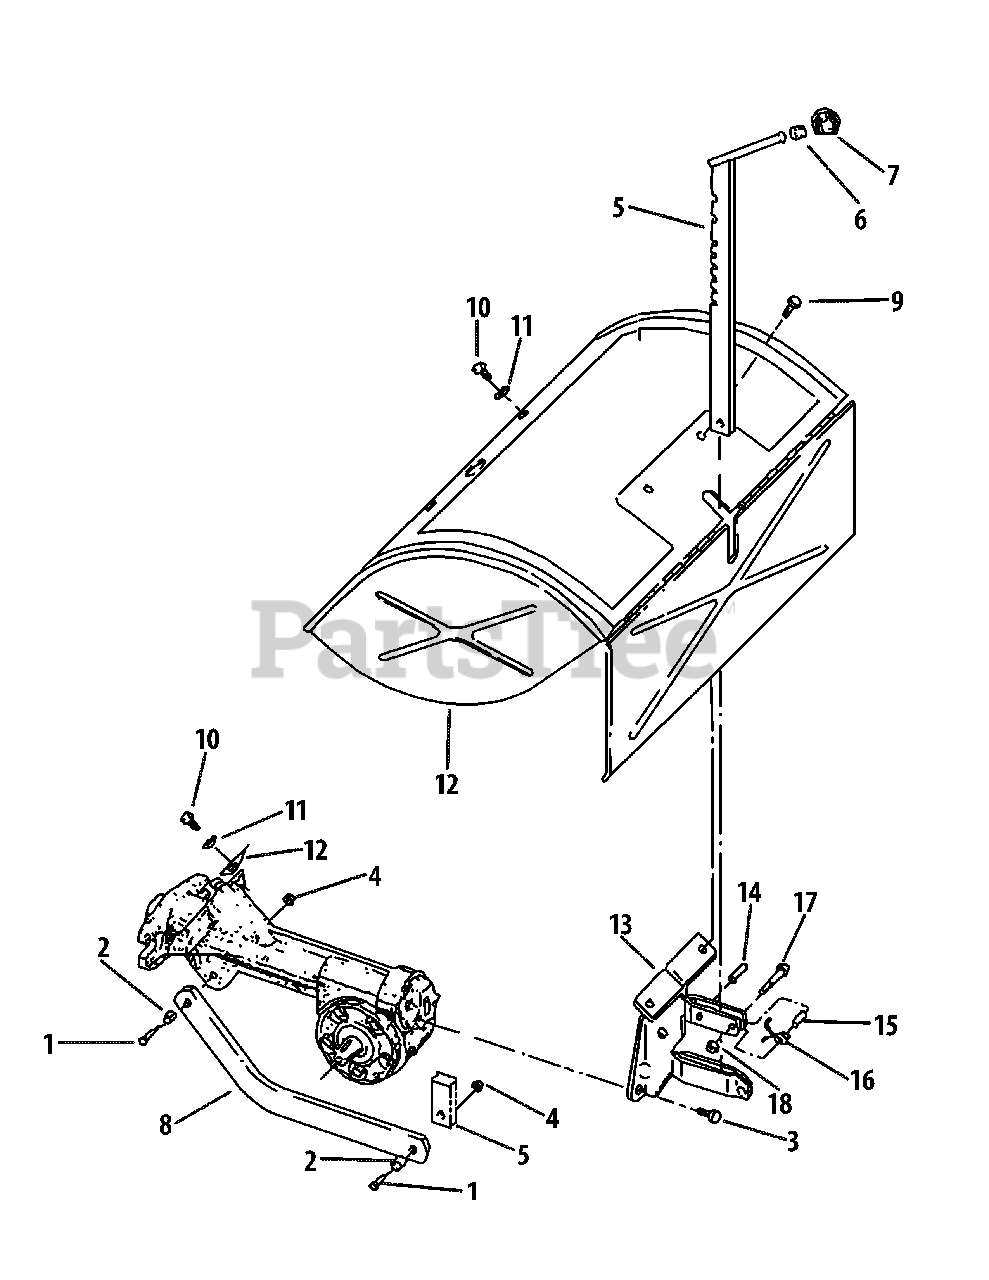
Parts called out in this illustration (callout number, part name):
1	Hex Bolt, 3/8 -16 x 1-1/4"
2	Bushing, 19/64"
3	Hex Flange Bolt, 5/16-18 x 5/8 "
4	Hex Nut, 3/8 "-16
5	Depth Regulator
6	Retaining Ring
7	Depth Regulator Knob
8	Depth Regulator Bar Drag
9	Thread-forming Screw,1/4-20 x 1/2"
10	Hex Flange Bolt, 5/16-18 x 3/4"
11	Flat Washer, 5/16"
14	Roll Pin (Spirol), 1/4" x 1"
15	Split Spacer
17	Hex Bolt, 1/4-20 x 1"
18	Locknut, 1/4"-20
